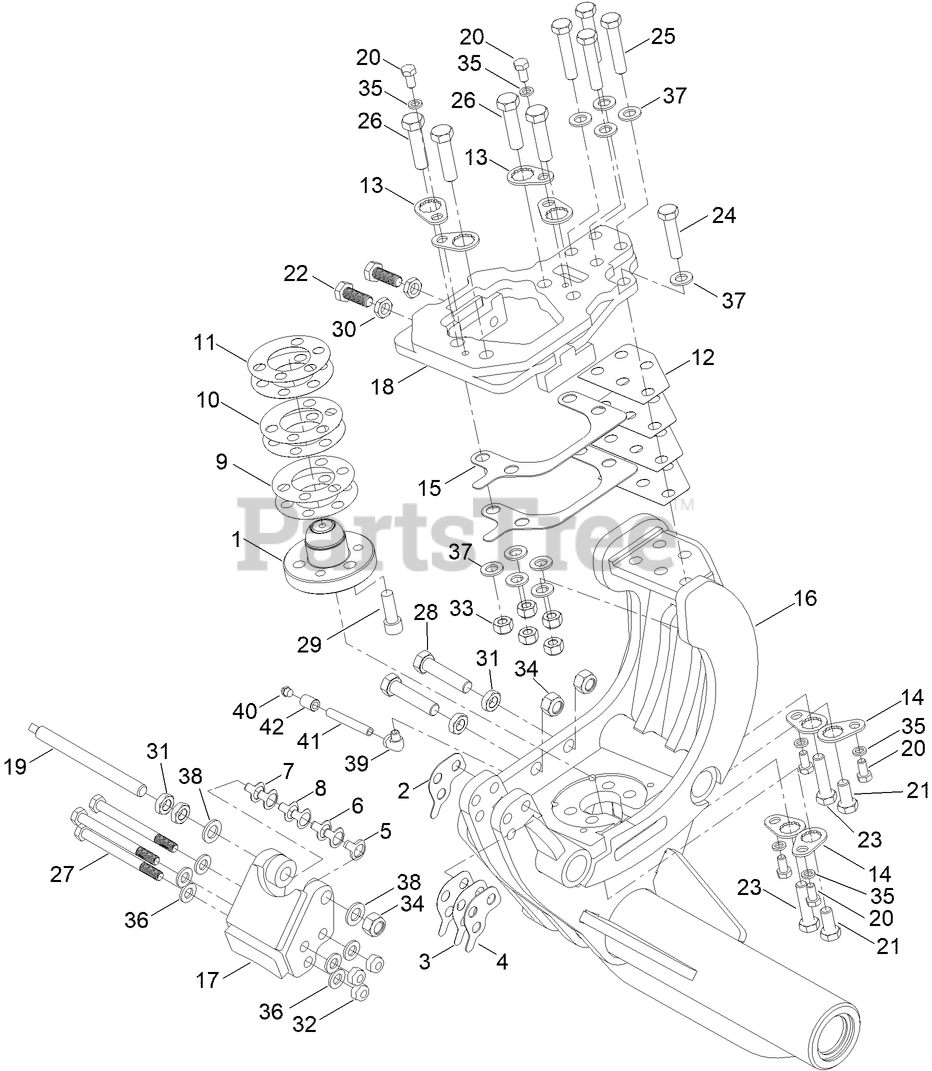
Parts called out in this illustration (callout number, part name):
1	PIN-KING, TRACKS
2	DIRECTION LIMITOR SHIM 18 GA.
3	DIRECTION LIMITOR SHIM 26 GA.
4	DIRECTION LIMITOR SHIM 16 GA.
5	SHIM 11 GA.
6	SHIM 16 GA.
7	SHIM 18 GA.
8	SHIM 26 GA.
9	SHIM KING PIN .005"
10	SHIM KING PIN .010"
11	SHIM KING PIN .015"
12	TOP MOUNTING PLATE SHIM 26 GA.
13	M16 BOLT LOCKING PLATE
14	M14 BOLT LOCKING PLATE
15	SHIM 16 GA.
16	FRONT RIGHT AND REAR LEFT ATTACHEMENT BR
17	FRONT RIGHT AND REAR LEFT DIR LIMITOR
18	FRONT RIGHT AND REAR LEFT TOP PLATE
19	ROD-THREADED
20	SCREW-HH
21	SCREW-HH
22	SCREW-HH
23	SCREW-HH
24	SCREW-HH
25	SCREW-HH
26	SCREW-HH
27	SCREW-HH
28	SCREW-HH
29	SCREW-HSH
30	NUT-HEX
31	NUT M16 THIN
32	NUT-HEX, LOCK
33	NUT-METRIC
34	NUT-METRIC
35	WASHER-FLAT
36	WASHER-FLAT
37	WASHER-PLAIN
38	WASHER-FLAT
39	ELBOW
40	FITTING-GREASE
41	NIPPLE
42	COUPLING-PIPE
